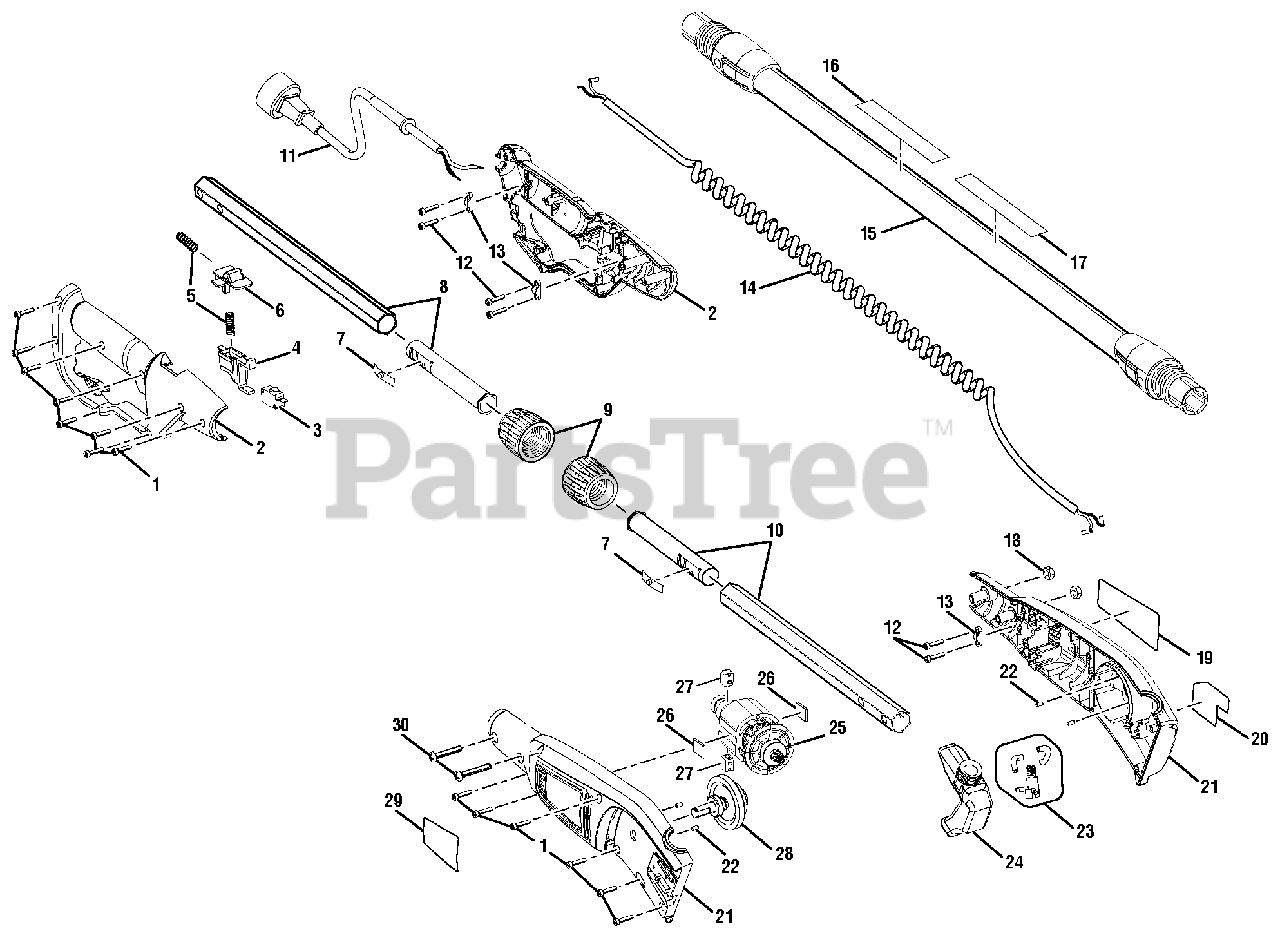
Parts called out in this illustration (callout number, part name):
1	Screw (M4 x 14 mm)
2	Handle Assembly
5	Compression Spring
6	Lock-off Button
7	Lock Spring
8	Upper Pole Shaft Assembly
9	Pole Coupler
10	Lower Pole Shaft Assembly
11	Power Cord
12	Screw (M4 x 12 mm)
13	Cord Clamp
14	Spring Cord Assembly
15	Pole Assembly
16	Data Label (French/Spanish)
17	Data Label (English)
18	Lock Nut (M5)
19	Logo Label (Left)
20	Warning Icon Label
21	Housing Assembly
22	Rubber Plug
23	Oil Pump Assembly
24	Oil Tank Assembly
25	Motor Assembly
26	Rubber Pad
27	Brush Assembly
28	Output Shaft Assembly
29	Logo Label (Right)
30	Screw (M5 x 35 mm)
